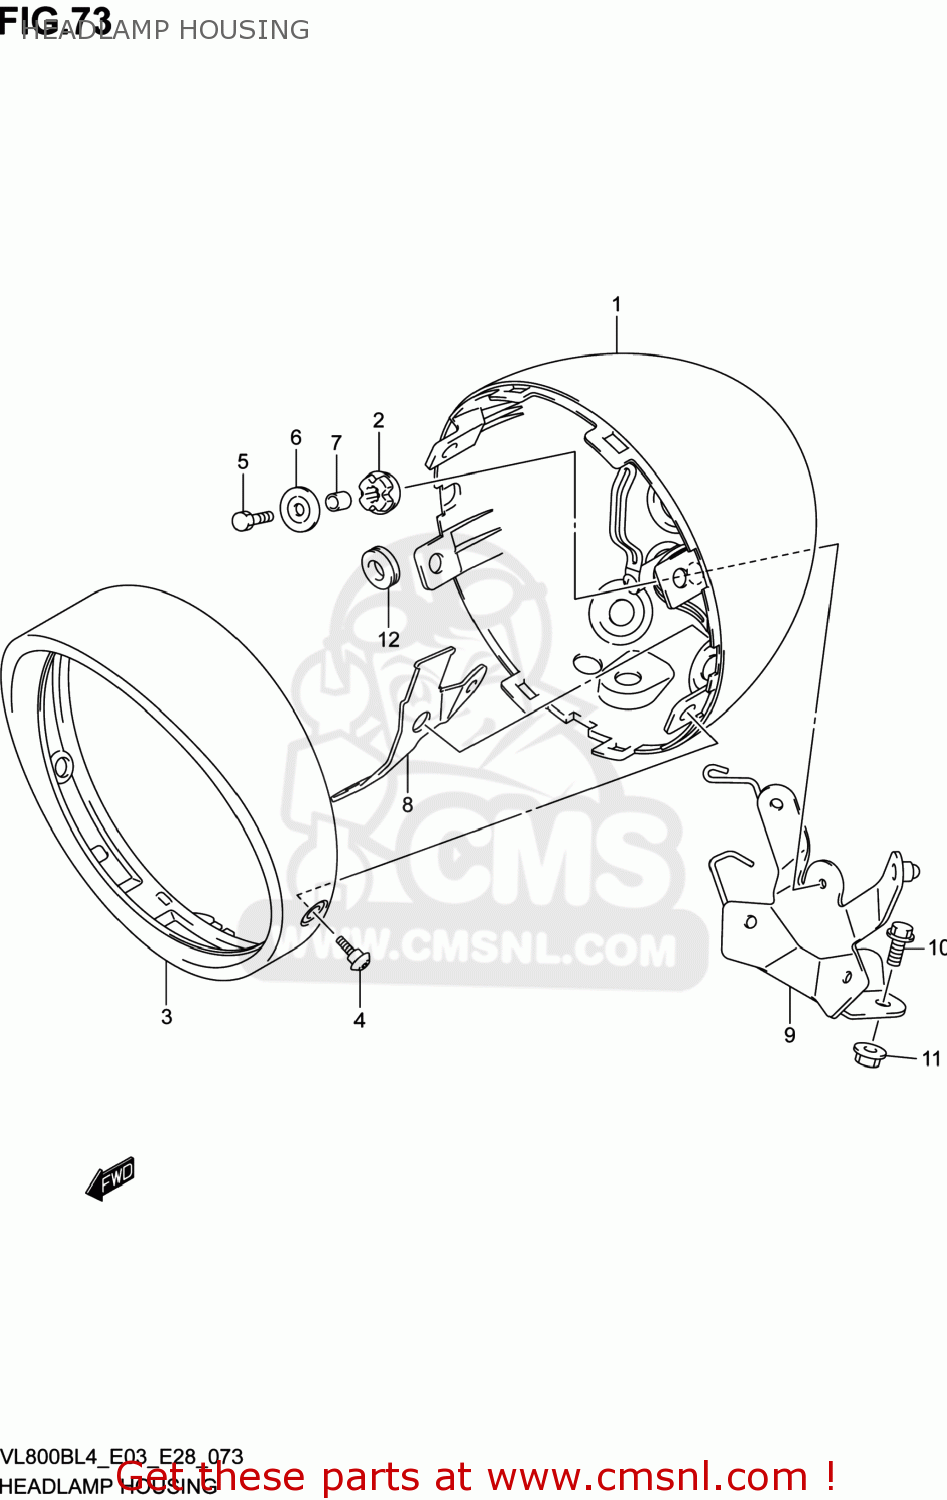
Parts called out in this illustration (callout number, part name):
1	HOUSING,HEADLAMP
2	CUSHION
3	COVER,HEADLAMP HSG
4	SCREW(5X16)
5	BOLT
6	WASHER(6.5X20X1.2)
7	SPACER(6.5X9X10)
8	PLATE,HEADLAMP HOUSING
9	BRACKET,HEADLAMP HOUSING
10	BOLT
11	NUT
12	CUSHION
